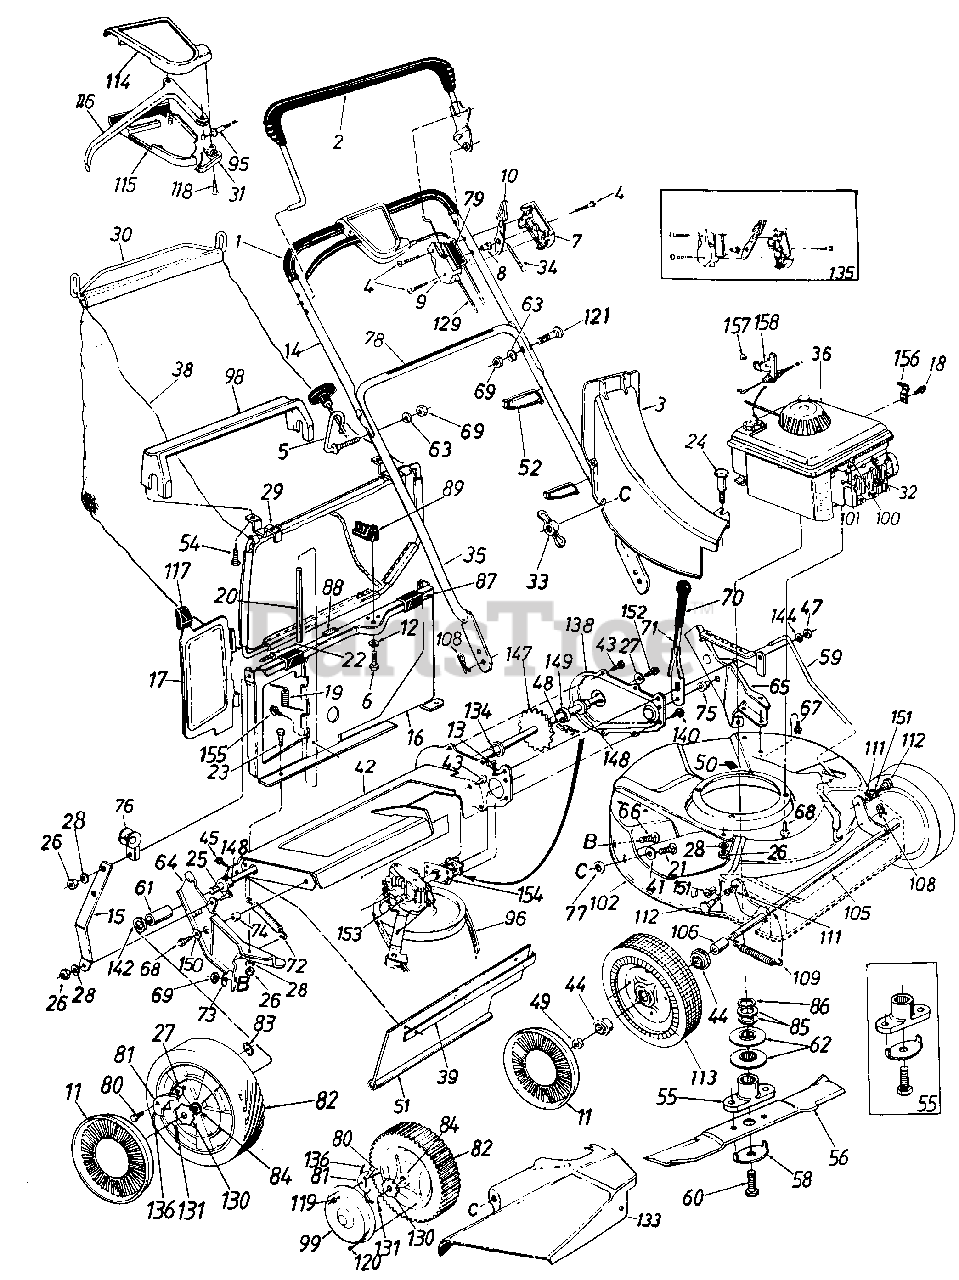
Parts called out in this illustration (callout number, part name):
1	GRIP-SHRINK-25 IN
3	CHUTE ASSY-TOP DISCH
4	SCREW-TRUSS MACH
5	SCREW-RECOIL HANDLE GUIDE
6	SCREW-HEX WASH 1/4-20X.75
7	PANEL HALF-CONTROL
8	PIN-CONTROL DISC
9	PANEL HALF-CLUTCH
10	LEVER-THROTTLE CONT-REV
11	HUB CAP
12	WASHER-SHAKE PROOF
13	PIN-COTTER-3/32 DIA X .75
14	HANDLE-UPPER-CHROME
15	BRACKET-PANEL SUP
16	PANEL ASSY-CATCHER
17	DOOR-TOP DISCHARGE
18	SCREW-HEX B-TAP #10 X .38
19	SPRING-TORSION
21	BOLT-CARRIAGE 1/4-20 X .62
22	SCREW-TRUSS MACH
23	SCREW-HEX 1/4-20 X .50
24	SCREW-SHLD
25	SCREW-HEX 1/4-20 C .62
26	NUT-HEX 1/4-20
27	WASHER-SPRING BELL
28	LOCK WASHER 1/4 DIA
29	FRAME-GRASSCATCHER
30	HANDLE-GRASSCATCHER
31	CAP-CABLE MTG
32	INSULATOR-SPARK PLUG
33	NUT-WING
34	WIRE-THROTTLE 58 LG
35	HANDLE-LOWER PAINTED
38	BAG-GRASS-CONV
39	STRIP-RETAINING
41	WASHER-FL-.344 ID X .62 OD X .033
42	AXLE ASSY-CHAIN
43	SCREW-HEX B-TAP 1/4 X .38
44	BEARING-BALL
45	SCREW-HEX WASH HD
47	NUT-HEX LOCK 3/8-24
48	#48 CHAIN 1/2 PITCH
49	NUT-HEX INS L-1/2-20
51	Rear Flap 3.75" x 17.30" Lg.
52	TIE-CABLE
54	SCREW-HEX AB-TAP
55	KIT-BLADE ADAPTER-SPLINED
56	BLADE-21IN
58	KIT-BLADE MOUNTING
59	ROD-HGT ADJ 1.50 X 19.42
60	SCREW-HEX 7/16-20 X 1.50
61	SPACER-.513 ID X .703 OD X .69
62	PULLEY HALF-SERRATED
63	WASHER-LOCK-5/16
64	BRACKET ASSY-HDLE-RH
65	BRACKET ASSY-HDLE-LH
66	BOLT-CARRIAGE 5/16-18 X .62
67	SCREW-HEX WASH HD 5/16-18X1/2
68	SCREW-HEX
69	NUT-HEX 5/16-18
71	LEVER-HGT ADJ
72	SPRING-EXTENSION
73	WASHER-BELL .337 X .867 X .057
75	SPACER-SHLD .500 X .100
76	GUIDE-ROPE
77	RETAINER-BOLT 1/4X.50 OD
80	SCREW-SHLD .342 DIA X .268
81	PAWL
82	WHEEL ASSY W/TIRE
83	NUT-FLAT WELD 1/4 X 20
85	WASHER-WAVE
86	WASHER-SERRATED
87	CLIP-PANEL BAG
88	STRIP-FOAM 1/4X1.0
89	KNOB-LOCKING
95	CABLE-CLUTCH X 50.0
96	BELT-V 3/8 X 31.0
98	HANDLE-BAG-BLACK
100	SCREW-HEX WASH HD TAP
101	CLIP-CASING
108	PIN-INTERN COT-5/16 DIA
109	SPRING-EXTENSION
111	WASHER-INTERN L 3/8 X.56 OD X .018
112	SCREW-SHLD
113	WHEEL ASSY W/TIRE 7X1.75BB
114	COVER-HALF-CONTROL
115	COVER-HALF CONT-LWR
116	LEVER-CONTROL
117	KNOB
118	SCREW-FL C-SUNK AB
121	BOLT-CARRIAGE-CURV 5/16-18 X 1.38
129	CABLE-CONTROL
130	RATCHET
131	PIN-COTTER-1/8 DIA X 1.00
133	DEFLECTOR-CHUTE
134	BEARING-HEX FLANGE
135	KIT-THROTTLE CONTROL
136	SPRING-NYLON
138	COVER-CHAIN
140	SCREW-HEX WASH SF TAPP
142	WASHER-FL
144	WASHER-FL-.385 ID X .87 OD X .06
147	SHAFT ASSY-REAR
148	BEARING-HEX FLANGE .506 ID
149	WASHER-FL-.531 X .930 OD X .050
150	WASHER-FL-.531 ID X 1.25 OD X 1.00
151	BEARING-NYLINER
152	SCREW-1/4-20 X .62
153	TRANSMISSION-COMP
154	BEARING-CUP HEX
155	SCREW-HEX B-TAP #10 X .38
156	CLAMP-CASING
158	BRACKET-CABLE
